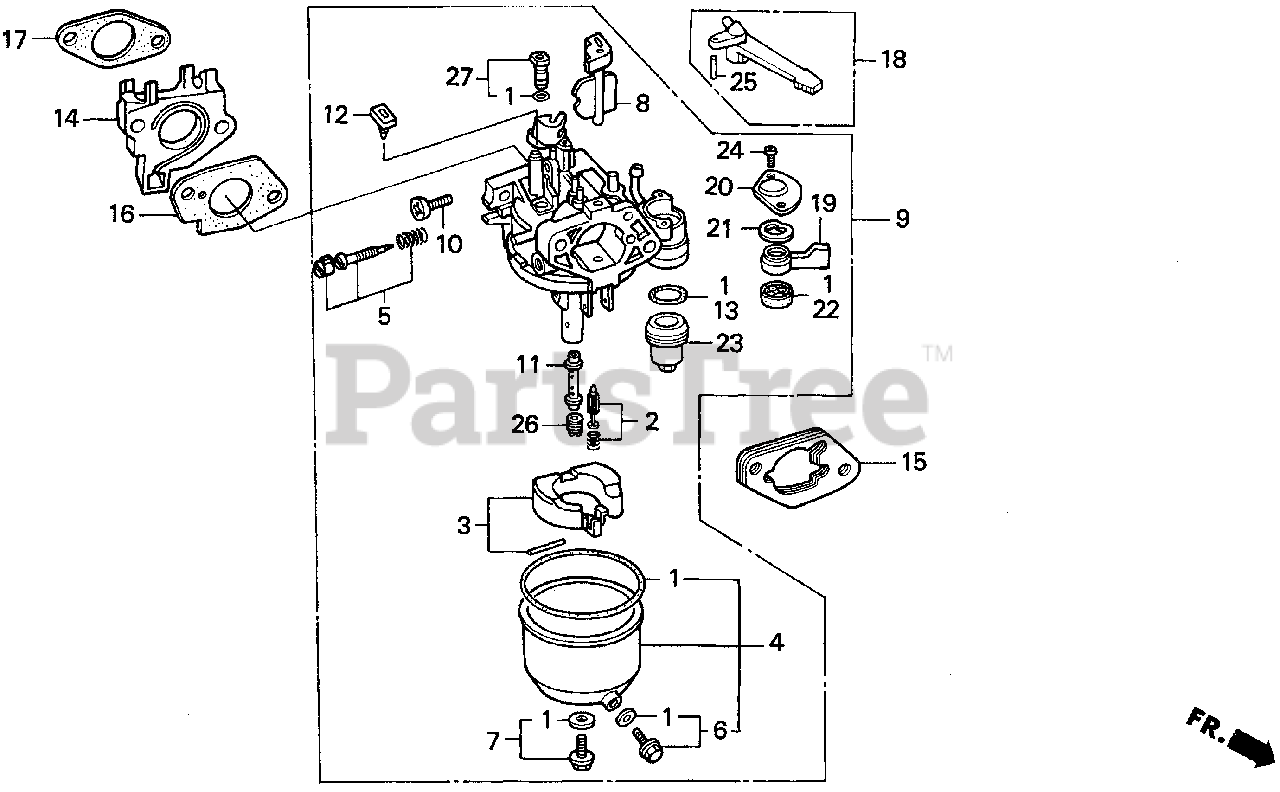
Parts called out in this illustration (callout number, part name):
1	GASKET SET
2	VALVE SET, FLOAT
3	FLOAT SET
4	CHAMBER SET, FLOAT
5	SCREW SET
6	SCREW SET, DRAIN
7	SCREW SET B
8	CHOKE SET
9	CARBURETOR ASSY. (BE75B B)
10	SCREW, THROTTLE STOP
11	NOZZLE, MAIN
12	COLLAR, SET
13	GASKET, FUEL STRAINER CUP
14	INSULATOR, CARBURETOR
15	SPACER, CARBURETOR
16	GASKET, CARBURETOR
17	GASKET, INSULATOR
18	LEVER, CHOKE (STD)
19	LEVER, VALVE
20	PLATE, LEVER SETTING
21	SPRING, VALVE LEVER
22	GASKET, VALVE
23	CUP, FUEL STRAINER
24	SCREW, PAN (3X6)
24	SCREW, PAN (3X8)
25	PIN, SPRING (2X12)
26	JET, MAIN (#80)
26	JET, MAIN (#82)
26	JET, MAIN (#85)
27	JET SET, PILOT (#40)
